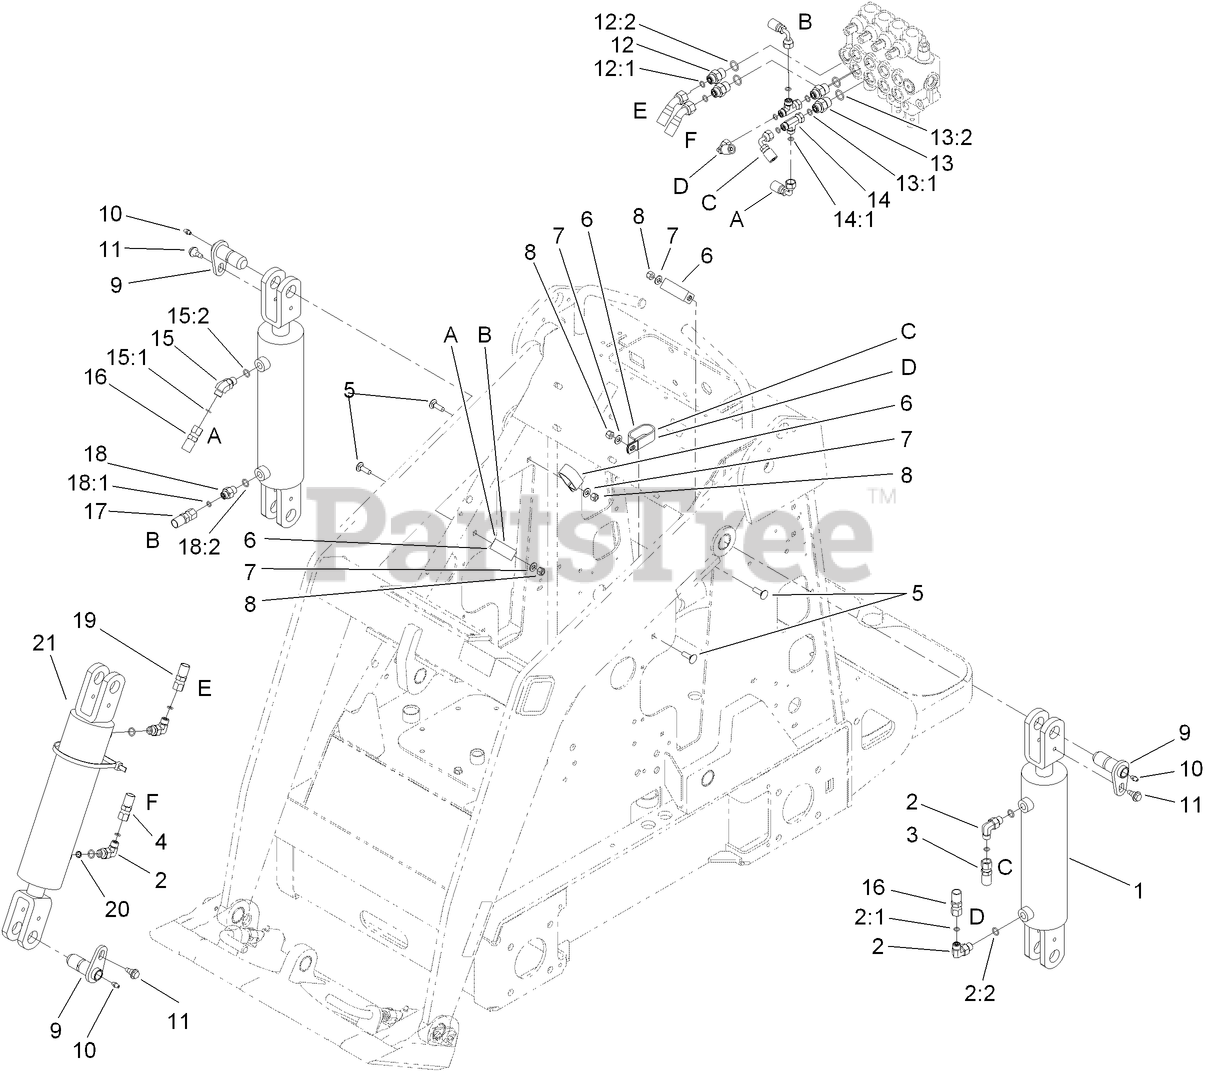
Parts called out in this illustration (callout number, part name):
1	CYLINDER-HYD
2	FITTING-ELBOW 90
2:1	O-RING
2:2	O-RING
3	HYD HOSE ASM
4	HOSE-HYD
5	BOLT-CARR
6	CLAMP-R, DOUBLE
7	WASHER-PLAIN
8	NUT-LOCK, NI
9	PIN-PIVOT
10	FITTING-GREASE
11	BOLT-SHOULDER
12	FITTING-STRAIGHT
12:1	O-RING
12:2	O-RING
13	FITTING-STR
13:1	O-RING
13:2	O-RING
14	FITTING-HYD
14:1	O-Ring
15	FITTING
15:1	O-RING
15:2	O-RING
16	HOSE-HYD
17	HOSE-HYD, RIGHT
18	FITTING-STRAIGHT
18:1	O-RING
18:2	O-RING
19	HOSE-HYD
20	ORIFICE-PORT INSERT, ONE WAY
21	TIE-CABLE
